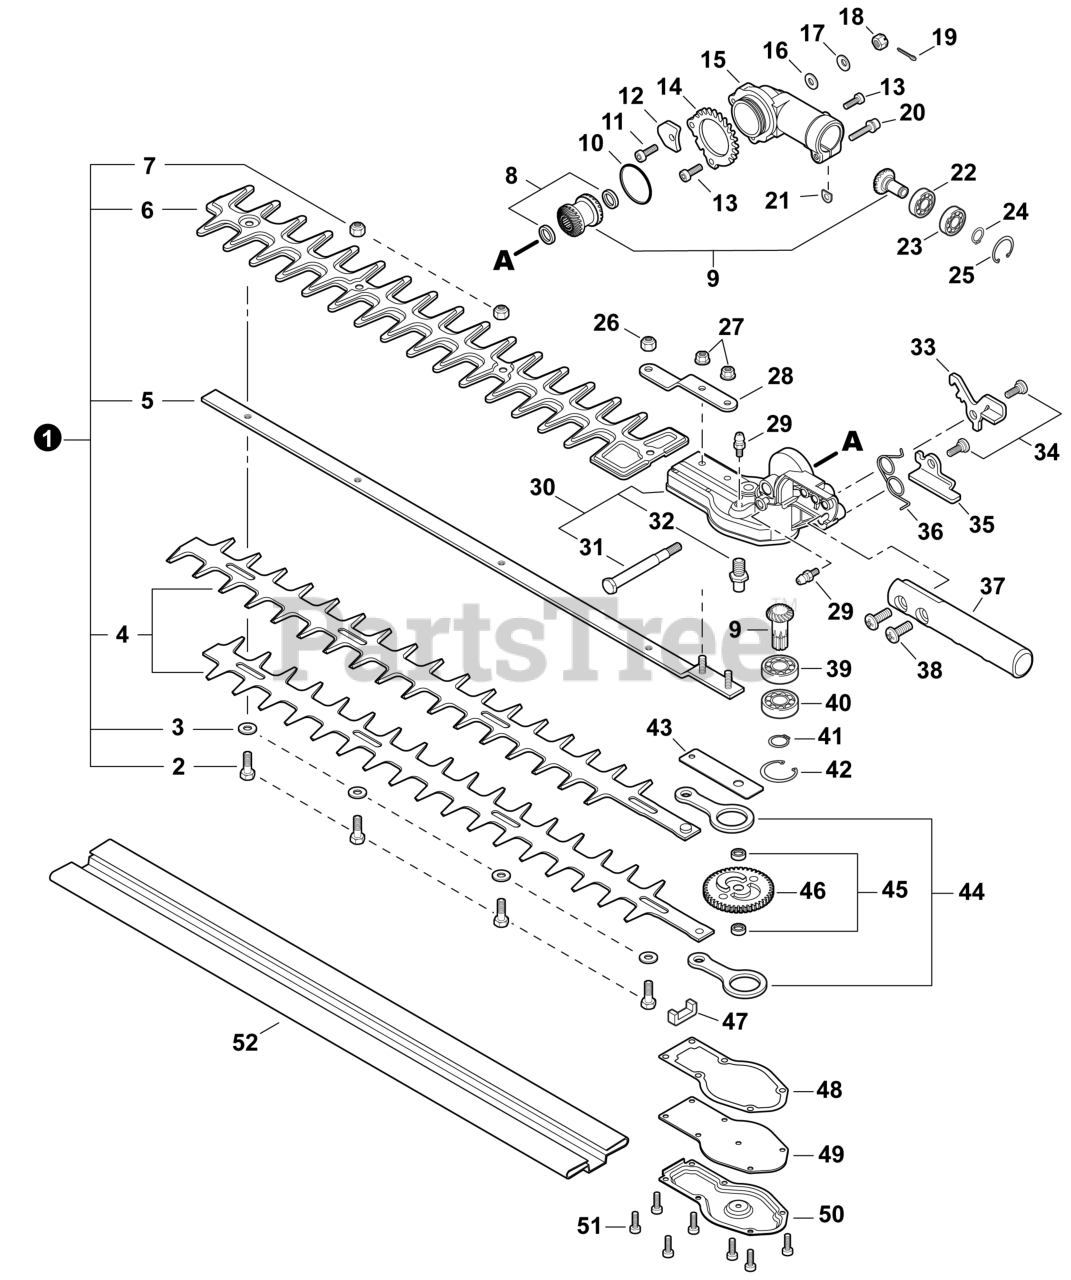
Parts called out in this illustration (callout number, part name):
1	CUTTER ASSY, 22"
2	BOLT M6x20
3	WASHER M6
4	CUTTER 22"
5	GUIDE BAR 22"
6	GUARD, CUTTER BLADE
8	COLLAR ?16x?10xL= 2
9	GEAR SET
11	SCREW M5x16
12	PLATE, STOPPER
13	BOLT 5x12
14	RING, LOCKING
15	HOUSING, UPPER GEAR CASE
16	WASHER 6.5x13x1
17	WASHER, CONE M6
19	PIN, COTTER ?1.6x15
20	BOLT M5x25
21	D-WASHER
22	BEARING, BALL 609
23	BEARING, BALL 609ZZ
24	RING, SNAP ?9
25	RING, SNAP 24
27	NUT, FLANGE M5
28	BRACKET, CUTTER
29	FITTING, GREASE
30	HOUSING ASSY, GEAR CASE
32	MAINSHAFT
33	LEVER, LOCK
34	BOLT M6
35	RELEASE, LOCK
36	SPRING, TORSION
37	LEVER, ADJUSTMENT
38	SCREW, TRUSS M6x20
39	BEARING, BALL 6001
40	BEARING, BALL 6001ZZ
41	RING, SNAP ?12
42	RING, SNAP 28
43	PLATE, GUIDE
45	SPACER ?11x?8x3.4
46	GEAR, CAM
47	PACKING, FELT
48	GASKET, GEAR CASE
50	COVER, GEAR CASE
51	BOLT 4x10
52	SCABBARD
